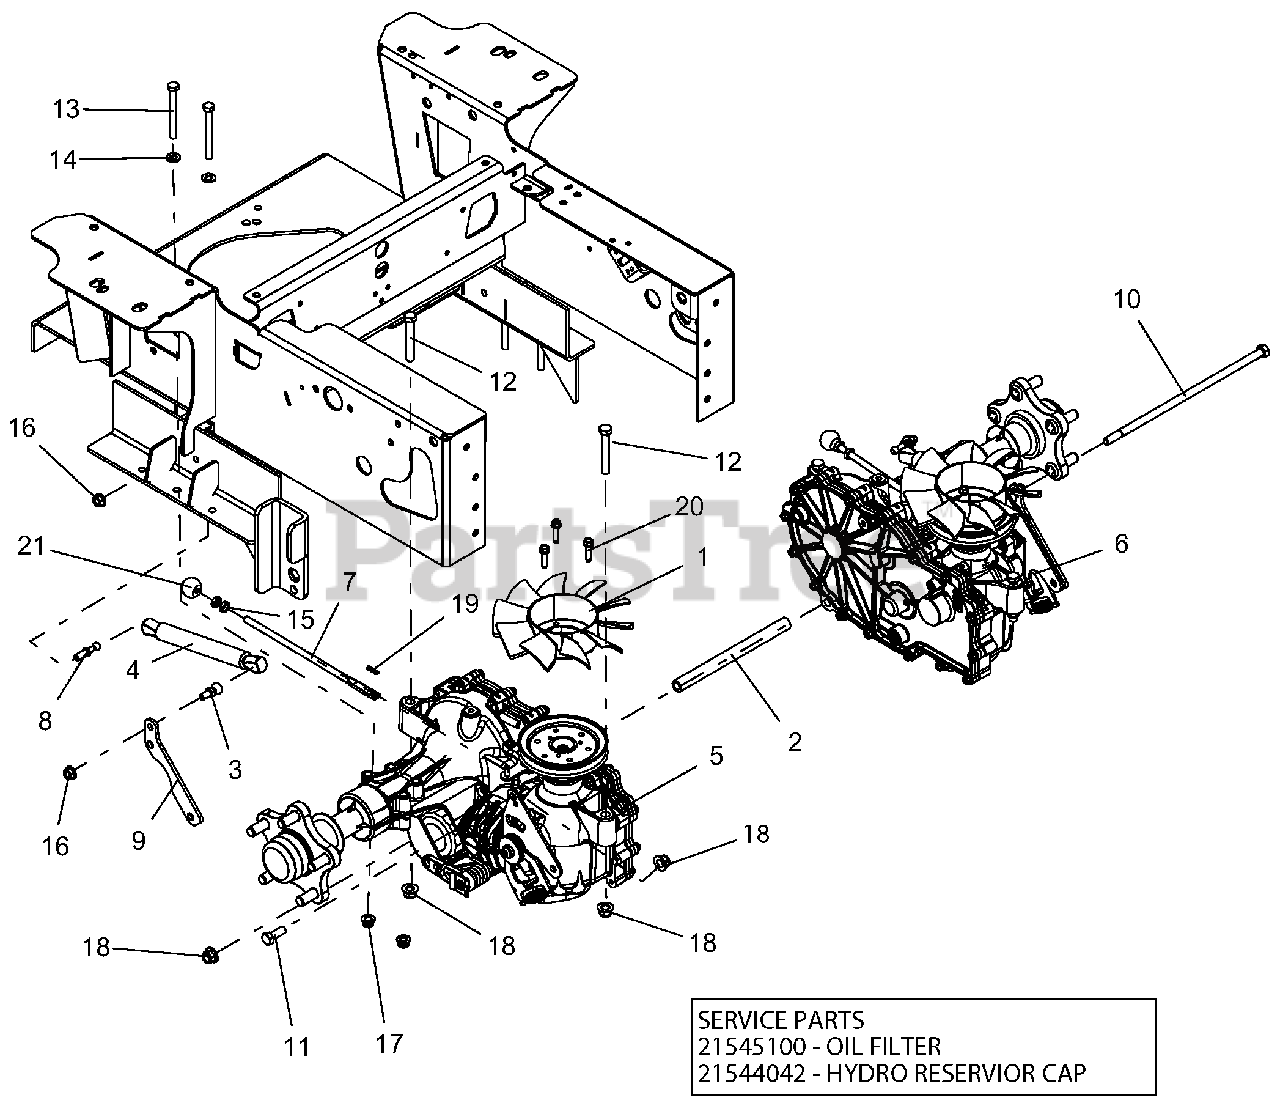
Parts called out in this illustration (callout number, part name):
1	FAN, 2800 SERIES COOLING
2	SPACER, 3/8 ID X 5/8 OD X 7.72
3	STUD-BALL
4	DAMPER,
5	TRANSAXLE, RH 3400
6	TRANSAXLE, LH 3400
7	LEVER, PT100 DUMP VALVE
8	STUD, BALL THREADED
9	TRANSMISSION DAMPER MTG PLATE - BLK
10	BLT, HEX .38-16X11.00 GR5 YWZC
11	BLT-HEX .38-16X1.00 GR5 YWZC
12	BLT-HEX .38-16X2.50 GR5 YWZC
13	BLT-HEX .31-18X3.00 GR5 YWZC
14	WSHR-FL-STL.344X.688X.065YWZC
15	NUT, JAM .312-18 YWZC
16	NUT, LK-TOP-FLG .312-18 YWZC
17	NUT-LK-NYL-FLG .31-18 YWZC
18	NUT-LK-NYL-FLG .38-16 YWZC
19	PIN-HAIR INT .06X.18X.77
20	SCR-TAP .25-20X1.00 HWH TR YZ
21	KNOB, BALL -BLACK .312-18
